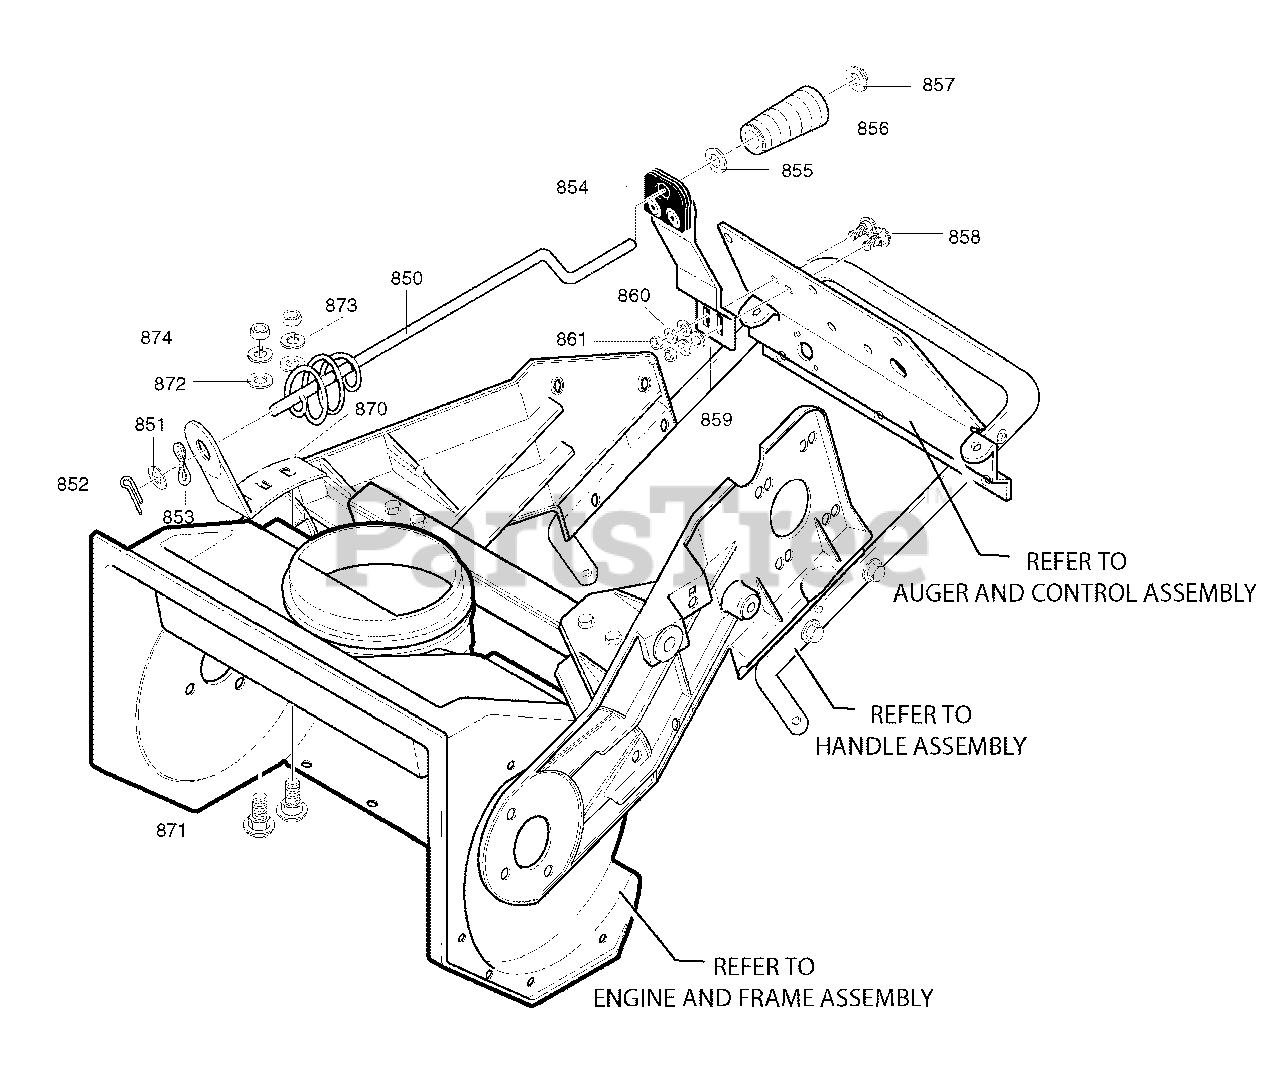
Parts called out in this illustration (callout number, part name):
850	ROD, Chute
851	WASHER, Flat, 13/32
852	PIN, Cotter
853	WASHER, Curved
854	CHUTE CRANK ASSEMBLY
855	WASHER, Flat, 13/32
856	KNOB, Sleeve
857	PUSHNUT, 3/8
858	BOLT, Carriage, 1/4-20 x 5/8
859	WASHER, Flat, 11/32 x 11/16
860	WASHER, 5/16 x 37/64
861	NUT, Hex, 1/4-20
870	BRACKET, Chute Rotate
871	BOLT, Carriage, 5/16-18 x 3/4
872	WASHER, Flat, 11/32 x 11/16
873	WASHER, Split Lock, 5/16 x 37/64
874	NUT, Hex, 5/16-18
